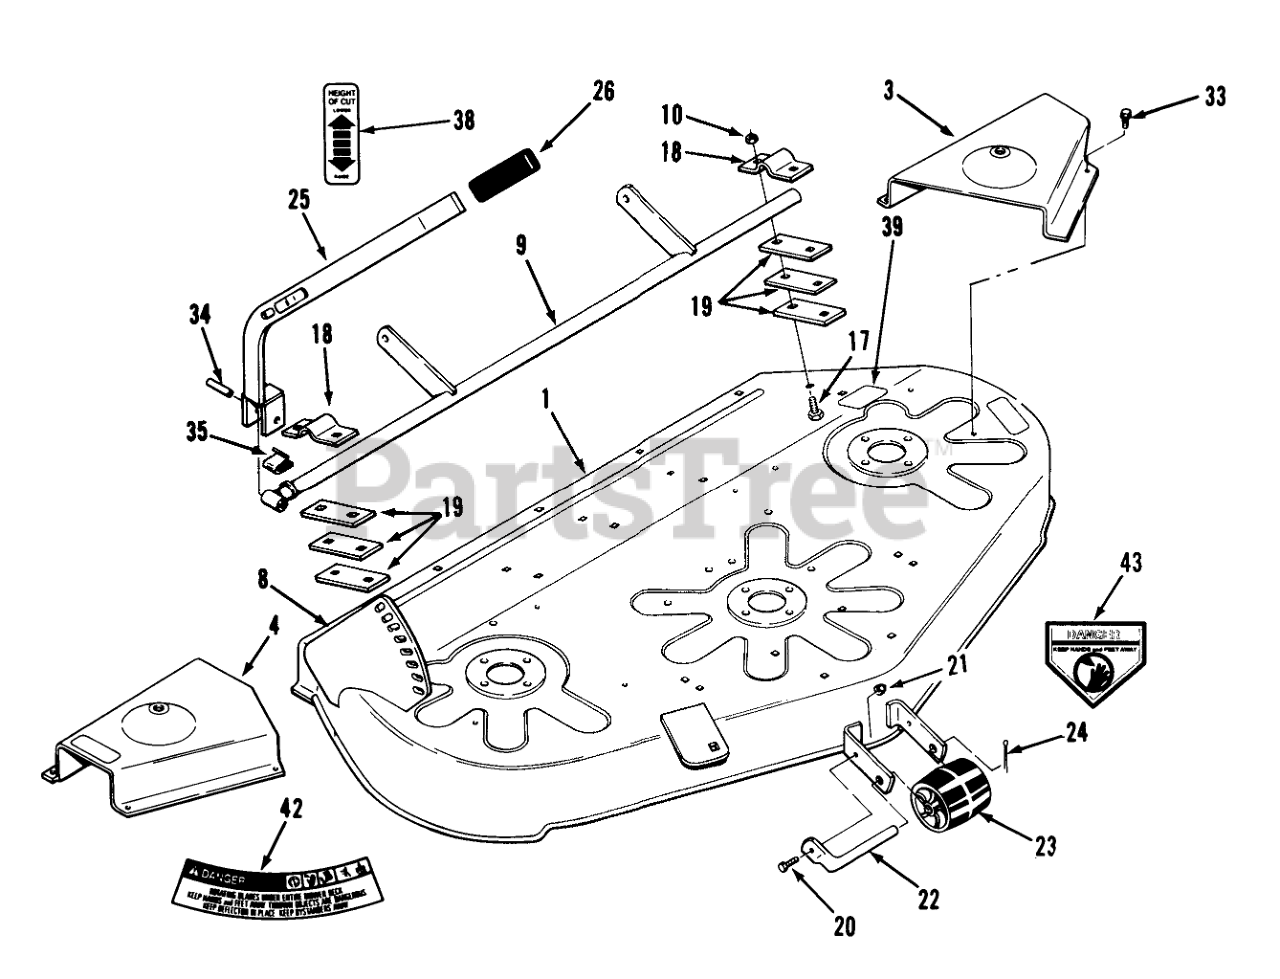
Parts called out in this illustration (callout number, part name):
1	Deck-Mower
3	Belt Cover LH
4	Belt Cover RH
8	QUADRANT 42RY MOWER
9	Lift Support
10	NUT-LOCK, NI
17	SCREW-CARR
19	Bar
20	SCREW-HH
21	NUT-LOCK
22	ROLLER-SHAFT
23	Roller
24	PIN-COTTER
25	Lever
33	Bolt
34	SPIROL PIN 3/8X1 1/2
35	CLIP-SPRING
38	DECAL-HOC
42	DECAL - DANGER
43	DECAL-DANGER
